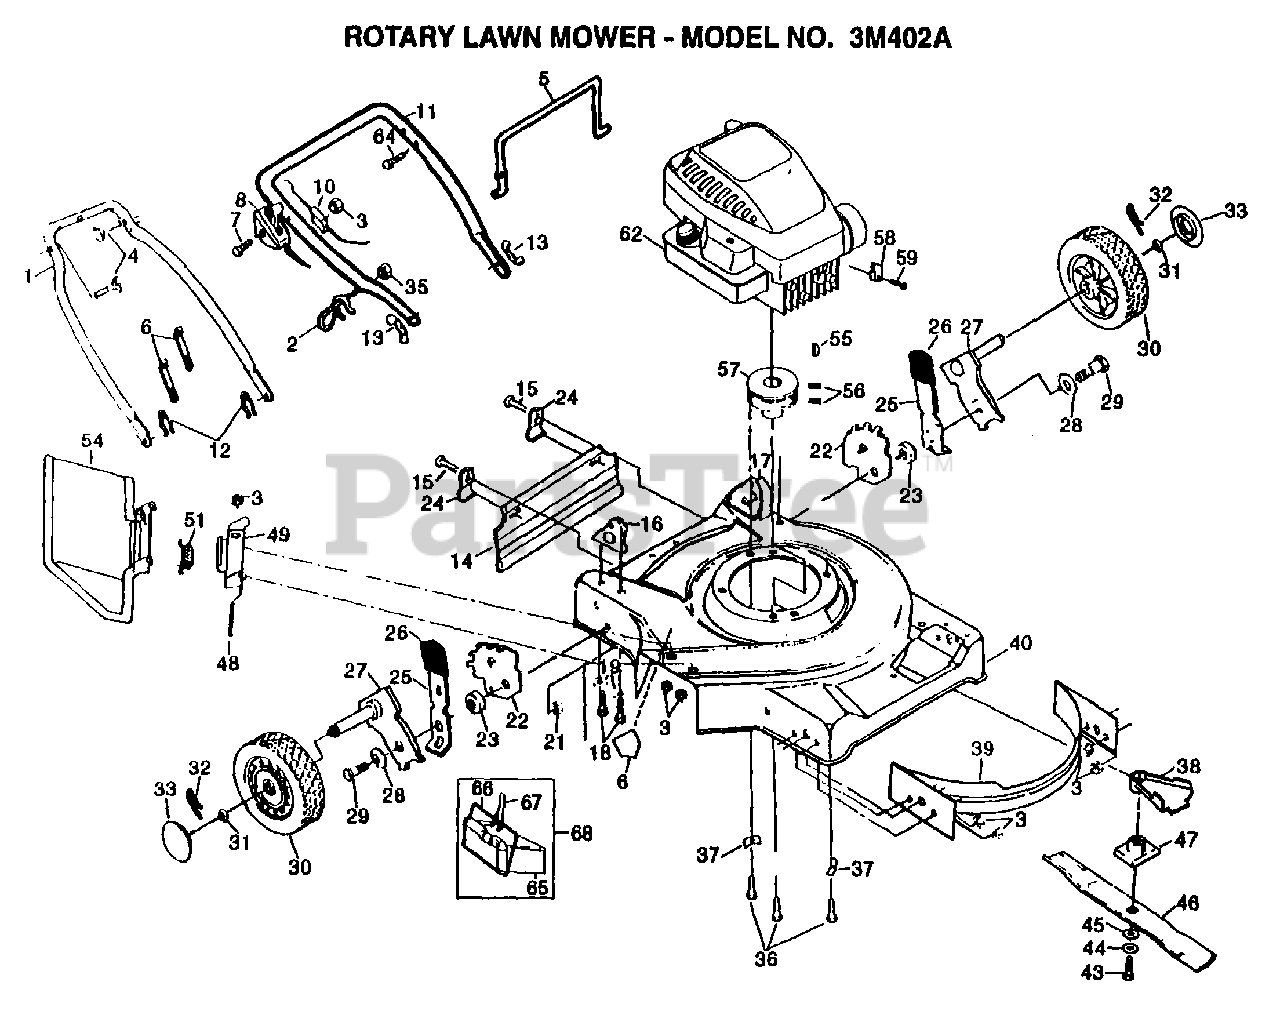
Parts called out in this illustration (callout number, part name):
2	ROPE GUIDE
4	BOLT.HANDLE.LM
5	CONTROL BAR
7	SCREW.HXHD.WASH.
8	"CONTROL, THROTTLE"
10	"CABLE,ENG ZONE CO"
12	HAIRPIN COTTER
13	"NUT,WING PM"
14	SKIRT.REAR.FGD.22
15	TAPPING SCREW
18	SCREW
19	STEEL WASHER
21	LOCKNUT PM
22	BRACKET.ADJ.9POS.
24	"BRKT,DEFL PM"
25	SPRING SELECTOR
26	KNOB PM
27	AXLE ARM
28	"WASHER, BELLEVIL."
29	BOLT SHLD 3/8-16
30	WHEEL.8X2.PR.RAD.
31	WASHER
32	RETAINER CLIP PM
33	HUB CAP
35	NUT
36	SCREW
39	BAFFLE FRONT 22SD
40	KIT.HSG.22SD.FWGD
43	"WASHER,HARDEN"
46	"BLADE.MULCH.22"""
47	ADAPTOR.BLADE.LM
48	ROD.HINGE.COMBI-C
49	BRACKET.HINGE.W/F
54	GUARD.DISCH.22SD.
55	HI PRO KEY PM
56	SCREW
57	ENGINE.PULLEY.FWG
58	CABLE CLAMP
59	SCREW PM
61	DECAL HYT
64	"SCREW,PAN HD"
66	BAIL.PLUG.MUL.22.
